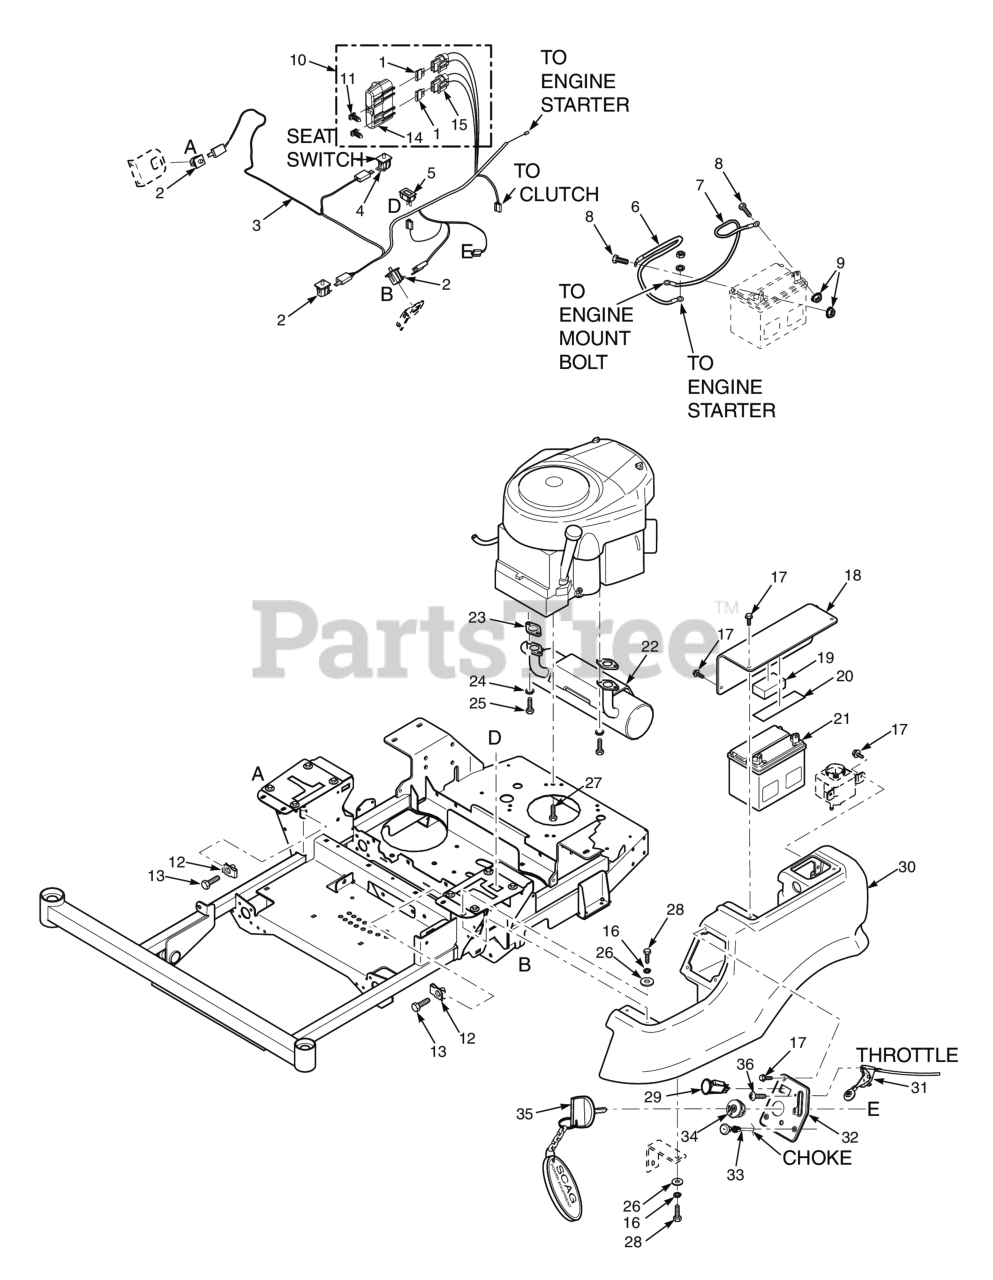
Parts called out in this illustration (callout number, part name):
1	FUSE, 20 AMP BLADE TYPE AUTOMOTIVE
2	Switch, Double Pole - Plunger
3	Wire Harness, Main
4	Switch, Double Pole - Twist
5	Hour Meter, Inductive
6	Battery Cable, 25" Red (Kawasaki)
7	Battery Cable, 27" Black (35BV & 37BV-EFI) - Briggs & Stratton
8	Bolt, Hex Head 1/4-20 x .5" Battery, (Not Available Through Scag)
9	Nut, 1/4 - 20 Hex
10	Double Fuse Assy.
11	Clip, Fuse Holder
12	U-Nut, 3/8-16 (short)
13	Bolt, Hex Head 3/8-16 x 1-1/4" with Thread Lock Patch
14	Cover, Sealed Double
15	Fuse Holder Assembly
16	Lockwasher, 5/16 (.317 x .586 x .078) Helical Spring
17	CAP SCREW, 1/4-20 X 1/2" SERRATED FLANGE HEX
18	Battery Cover
19	Pad, Battery - Rubber
20	Rubber Pad
21	Battery, 350 CCA (not available through Scag)
22	Muffler, Kawasaki FS/FX
22	Muffler, Kohler
23	Exhaust Gasket
24	Lockwasher
25	Bolt
26	Flatwasher, 5/16-.375 x .875 x .083 (35BV & 37BV-EFI)
27	Bolt, Hex Head Self-Tap 3/8-16 x 1-1/4" (Kohler x3 - 25EFI, Kohler x4 - 29EFI)
27	Bolt, Hex Head 3/8-16 x 1-1/4", Kawasaki FX / FS
28	BOLT, SERRATED FLANGE HEX HEAD 5/16-18 X 3/4"
29	Switch, PTO - 10 Amp
30	Tank, LH - SPZ
31	Throttle Cable, Briggs & Stratton
32	INSTR PANEL W/ DECAL, SFZ
33	Choke Cable, Briggs & Stratton
34	Ignition Switch
35	Key w/Shroud Only
35	Key, Assembly w/Fob
36	Bolt, Carriage #10-24 x 1/2"
